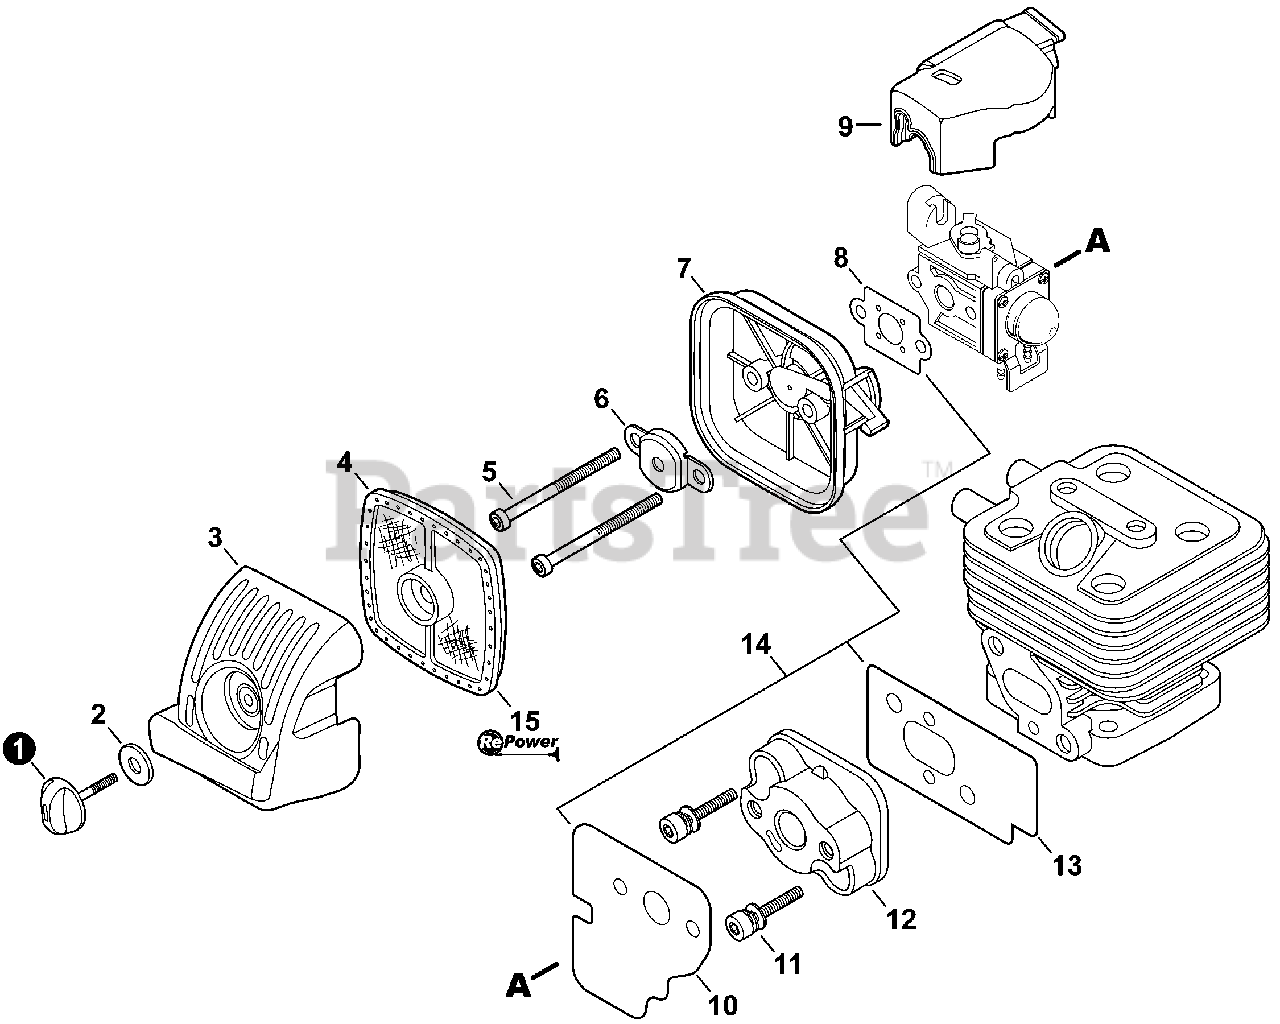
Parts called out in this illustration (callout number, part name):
1	THUMBSCREW
2	WASHER 5.5×16×0.8
3	COVER, AIR FILTER
4	FILTER, AIR - DOUBLE LAYER
5	BOLT 5×60
6	PLATE, PREVENT
7	CASE ASSY, AIR FILTER
8	GASKET, INTAKE
9	COVER, DUST
10	GASKET, INTAKE
11	BOLT 5×25
12	INSULATOR, INTAKE
13	GASKET, INTAKE
14	GASKET KIT
15	TUNE-UP KIT - REPOWER
